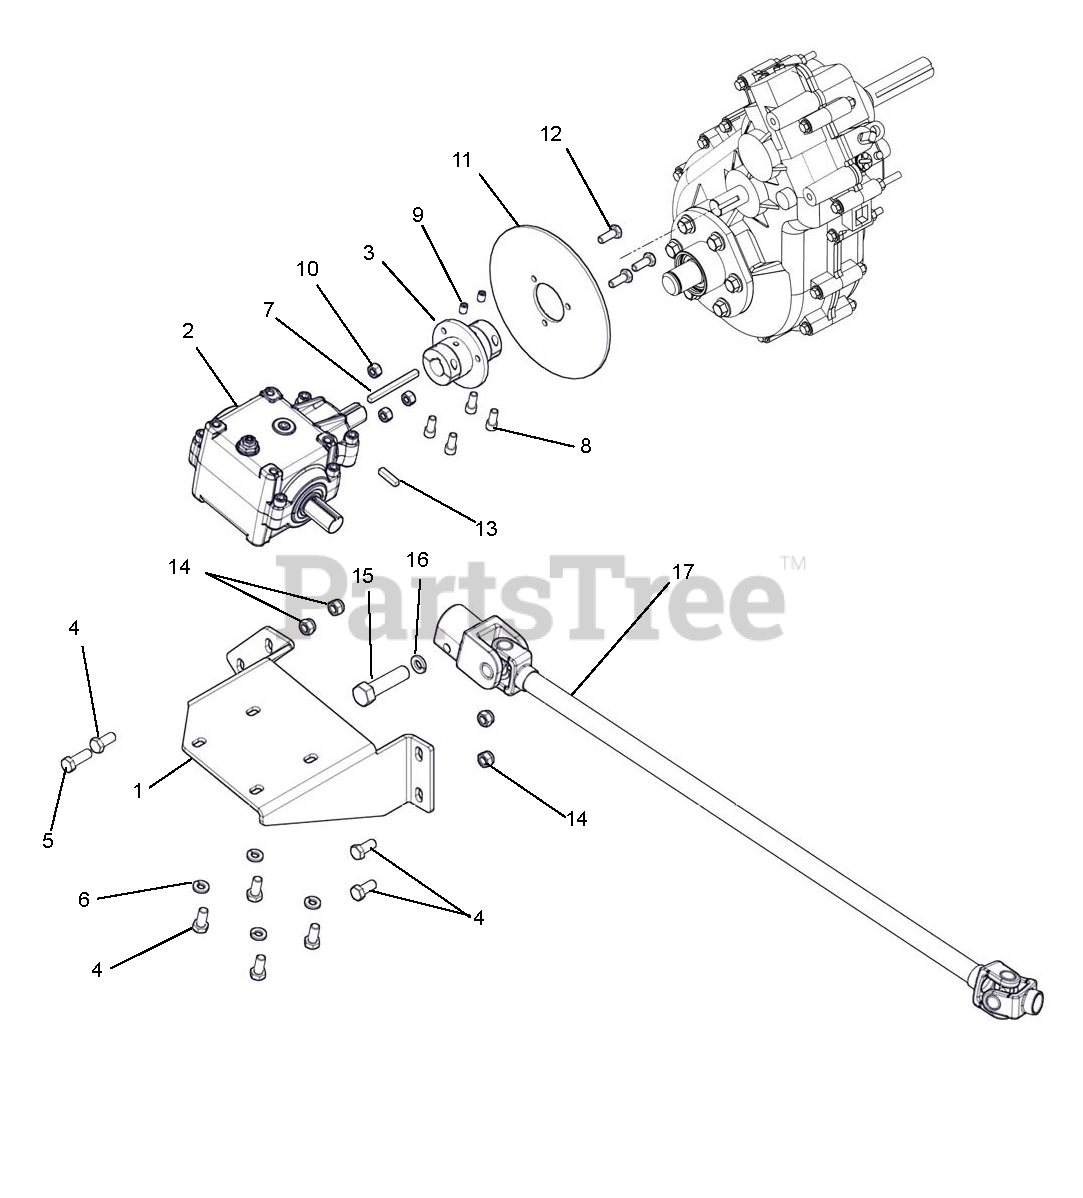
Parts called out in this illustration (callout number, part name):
1	4X4 MOUNT PLATE
2	GBOX MODEL R100 1.5TO1 RATIO
3	COUPLER, SHORT
4	@BLT-HEX .31-18X.75 GR5 YWZC
5	@BLT-HEX .31-18X1.00 GR5 YWZC
6	@WSHR-LK .31X.078 REG YWZC
7	KEY, .188 X .188 X 2.50 SQ
8	HSHCS 1/4-28X5/8
9	SCR-SET .25-28X.375 SK CUP
10	@NUT-LK-CTR .25-20 YWZC
11	DISK, PARK BRAKE
12	@BLT-HEX .25-20X.75 GR5 YWZC
13	KEY 3/16 X 7/8
14	@NUT-LK-NYL .312-18 YWZC
15	@BLT-HEX .38-16X2.00 GR5 YWZC
16	@WSHR-LK .38X.094 REG YWZC
17	REAR HALF DRIVELINE 4X4 ST
